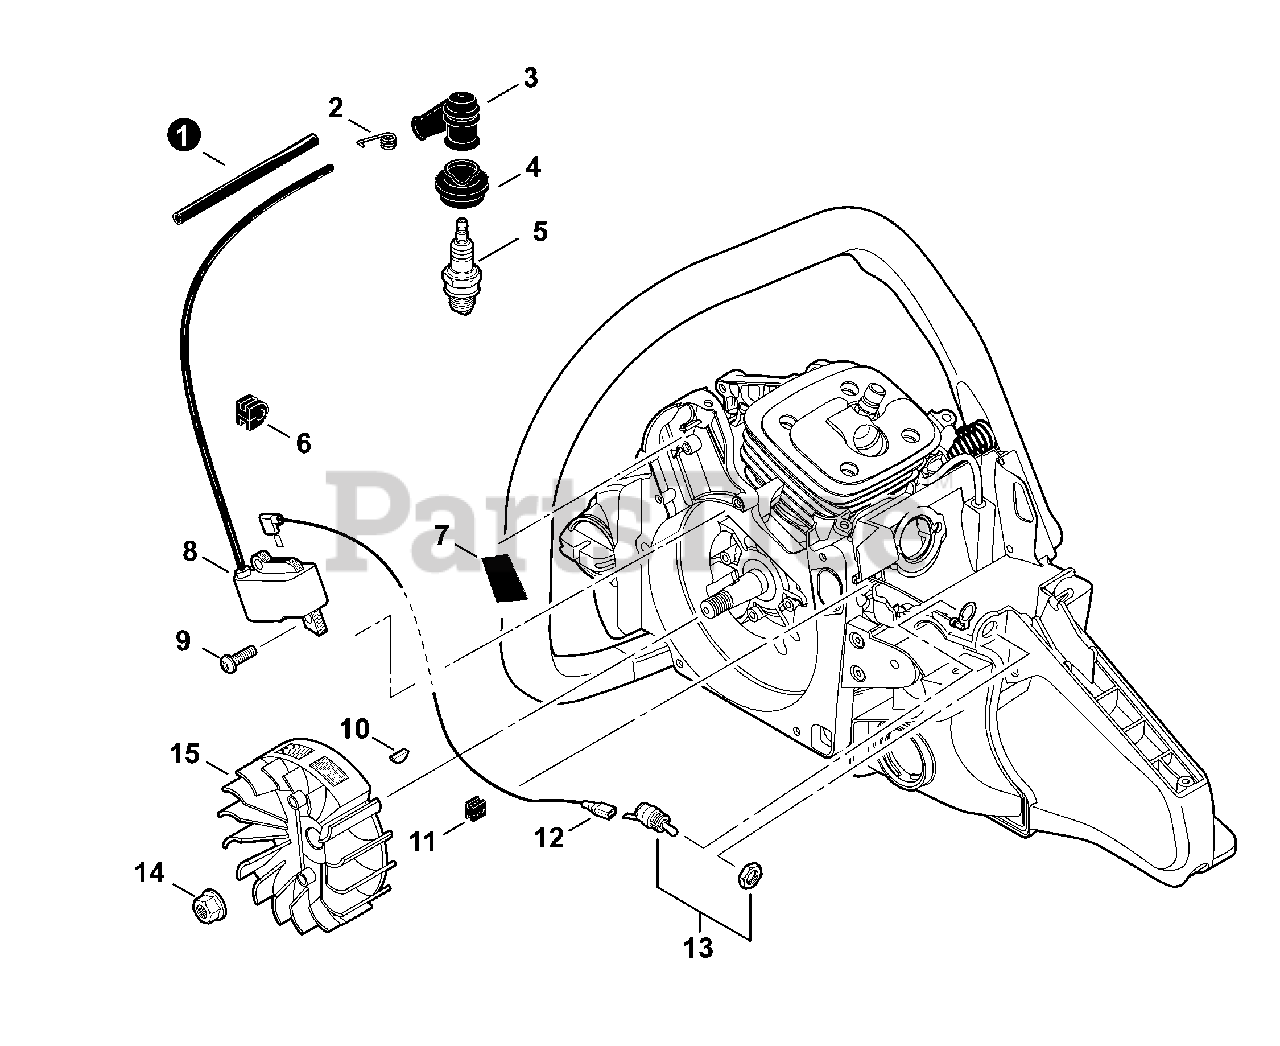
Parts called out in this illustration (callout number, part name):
1	TUBE, IGNITION COIL 6×7.2×70
2	TERMINAL, SPARK PLUG
3	CAP, SPARK PLUG
4	SEAL, SPARK PLUG
5	SPARK PLUG - BPMR8Y
7	CUSHION
8	COIL, IGNITION
9	BOLT, TORX 5×16
10	KEY, WOODRUFF
11	GROMMET, LEAD
12	LEAD - IGNITION L= 280
13	SWITCH, ON-OFF
14	NUT, FLANGE M8
15	FLYWHEEL
